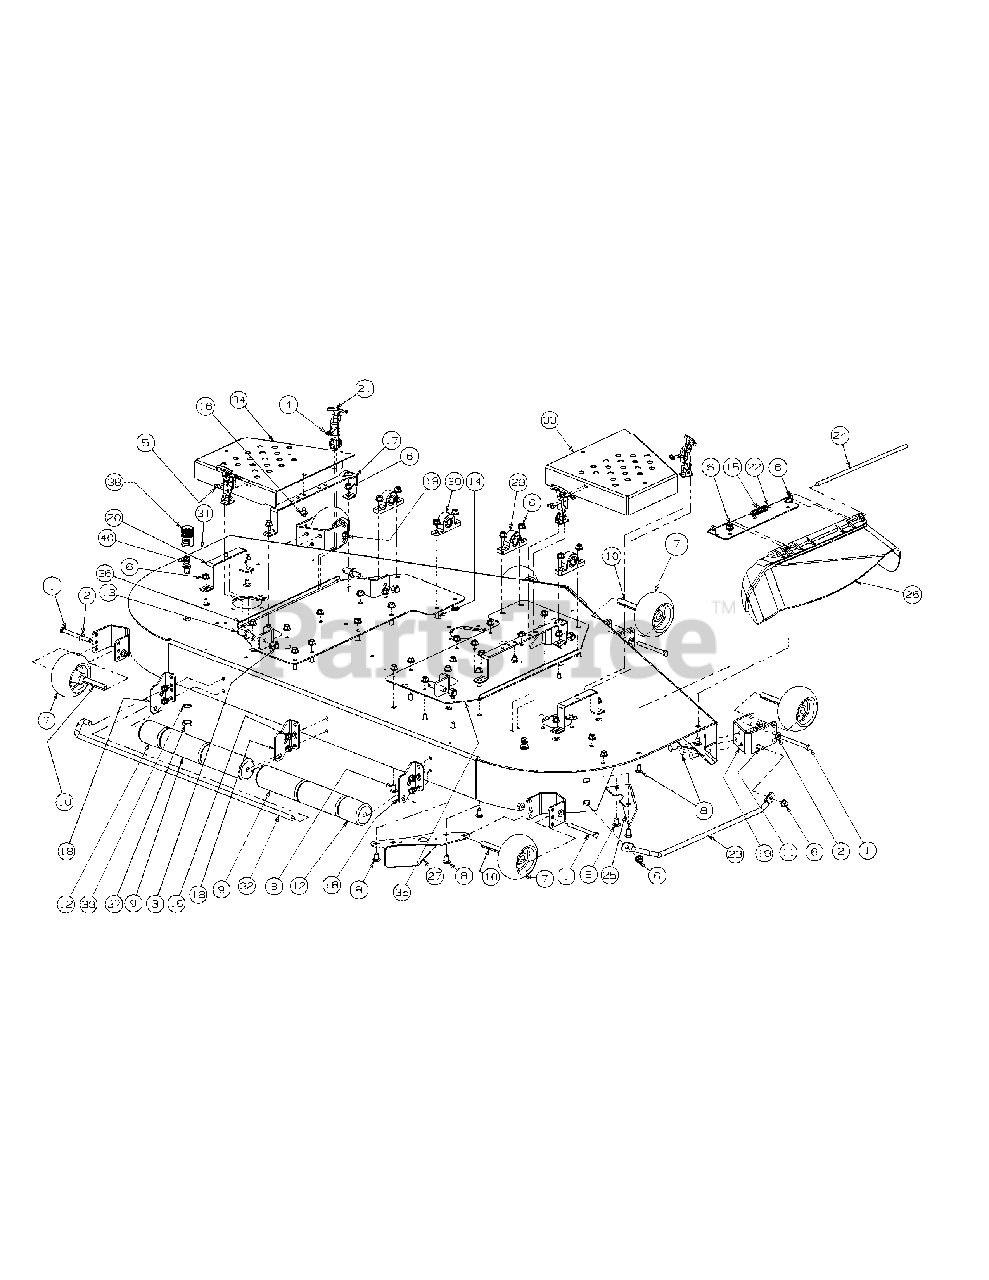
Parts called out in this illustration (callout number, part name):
1	Hex Cap Screw, 3/8-16, 3.75
2	Flat Washer, 3/8
3	Lock Nut, Nylon Insert, 1/2-13
4	Lock Nut, Nylon Insert, #10-32
5	Phillips Head Screw, #10-32 x 1/2
6	Flange Lock Hex Nut, 3/8-16
7	Complete Wheel, 5.00 Dia.
8	Carriage Bolt, 3/8-16 x .75 Lg.
9	Front Roller
10	Wheel Spacer
11	Carriage Bolt, 3/8-16 x 1
12	Grass Catcher Roller
13	Pin, 5/8 Dia. x 1.2 Lg.
14	Carriage Screw, 3/8-16 x 1.25
15	Torsion Spring, 0.4ID x 2.16Lg
16	Hex Index Washer Screw, 3/8-16, .5
17	Belt Cover Support
18	Deck Roller Mount Bracket
19	Anti-Scalp Wheel Front Mount Bracket
20	Outer Belt Cover Support Assembly
21	T-Handle Latch Draw
22	Chute Bracket
23	Finger Guard
24	Pin, .375 x 14.06
25	Chute Bracket
26	Chute Deflector
27	Discharge Baffle Weldment
28	Nut, 1/2-13, Flangelock
29	Pillow Block, Steel
30	Pillow Block, Bronze
31	72 Deck Assembly
32	J-Hook w/ Threaded Roller
33	Right Hand Deck Belt Cover
34	Left Hand Deck Belt Cover
35	Right Hand Deck Weldment Bracket
36	Left Hand Deck Weldment Bracket
37	Hex Nut, M16-1.5
38	Water Nozzle Adaptor
39	Lock Washer, 17 x 23.8 x 1.95
40	Deck Water Nozzle
